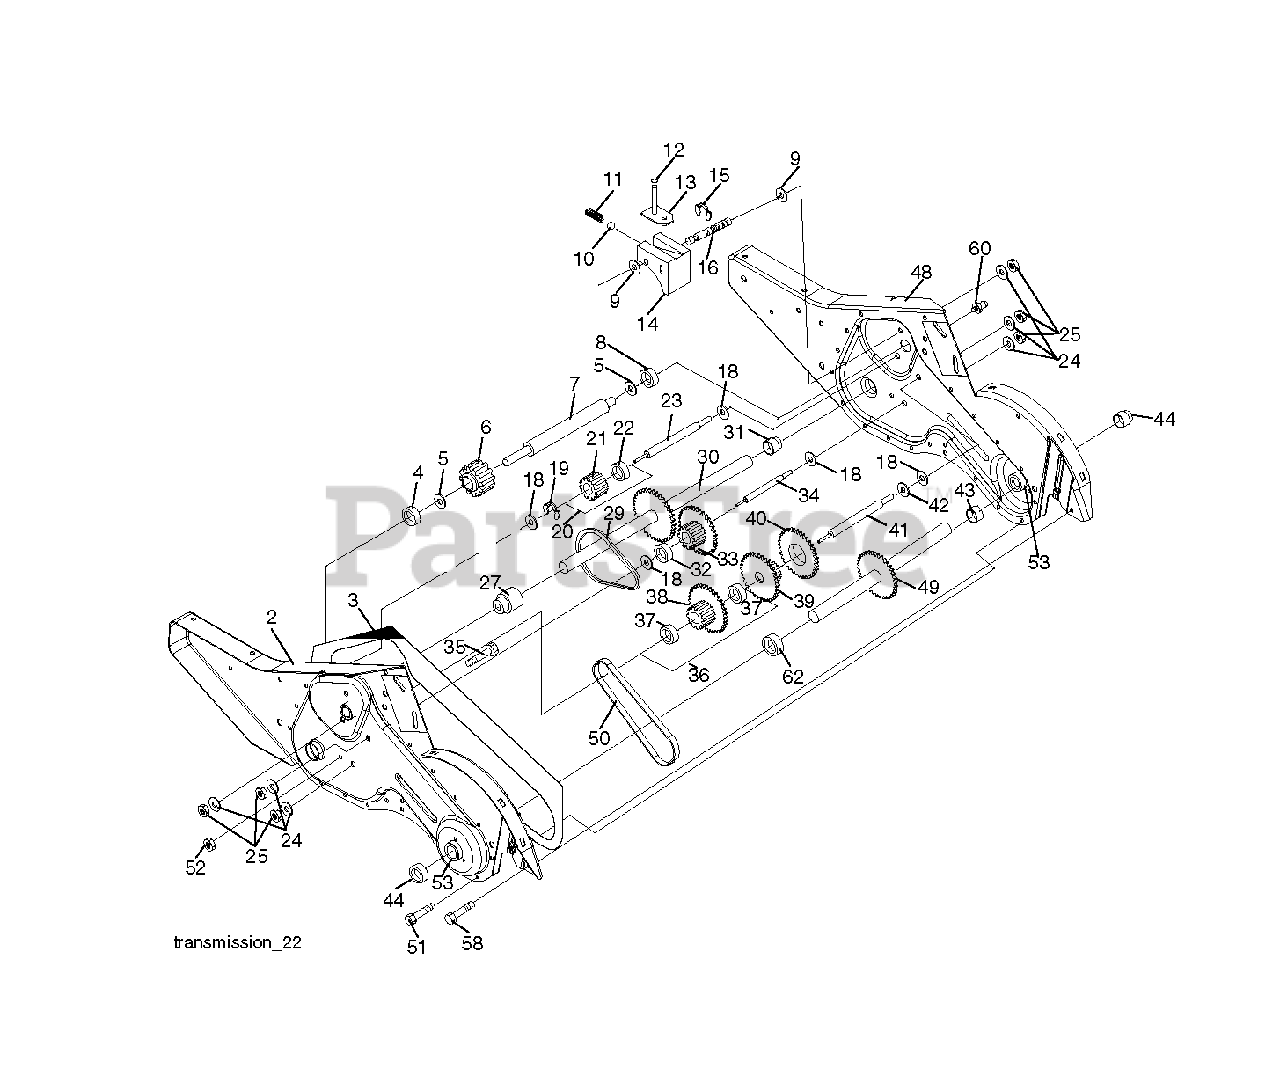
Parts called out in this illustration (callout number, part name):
2	GEARCASE.ASM.CRT.LH.W/BEARING
3	GASKET.GEARCASE.CRT/DRT.TILLER
4	NEEDLE BRNG LT
5	THRUST WASHER
6	GEAR.PINION.INPUT
7	SHAFT.INPUT."D".TILLER
8	BEARING TI
9	WASHER, SEAL (2 2)
10	STEEL BALL KIT
11	SPRING-SHIFT CRT
13	BRACKET ASM.SHIFT.CRT
14	SHIFT FORK TI
16	SHAFT.SHIFTER.TILLER
20	GEAR ASSY CRT
21	GEAR-REV IDLR CRT
22	NEEDLE BEARING TI
24	LOCKWASHER
25	NUT.ASF.HEX.7/16
27	BEARING.GROUND.DRIVE
30	GROUND SHAFT ASS'Y
31	BEARING, SHAFT RH CRT
33	SPRCKT 8 GEAR CRT
34	SHAFT.SECONDARY.REDUCTION.CRT
35	SCRW WHIZ LOK CRT
36	SPROCKET.ASM.W/BEARING.TILLER
37	BEARING
38	SPROCKET, TINE
41	SHAFT.REDUCTION.TILLER
42	BRNG RACE T
44	SEAL ASM, OIL
48	GEARCASE.ASM.CRT.RH.W/BEARING
49	SHAFT.ASM.TINE
50	CHAIN.TILLER
51	SCREW
53	BEARING KIT
58	BOLT SHOULDER 1/4-20 UNC X.875
60	FITTING.GREASE.TAPERED
62	SPACER.1.015X1.50X.650
